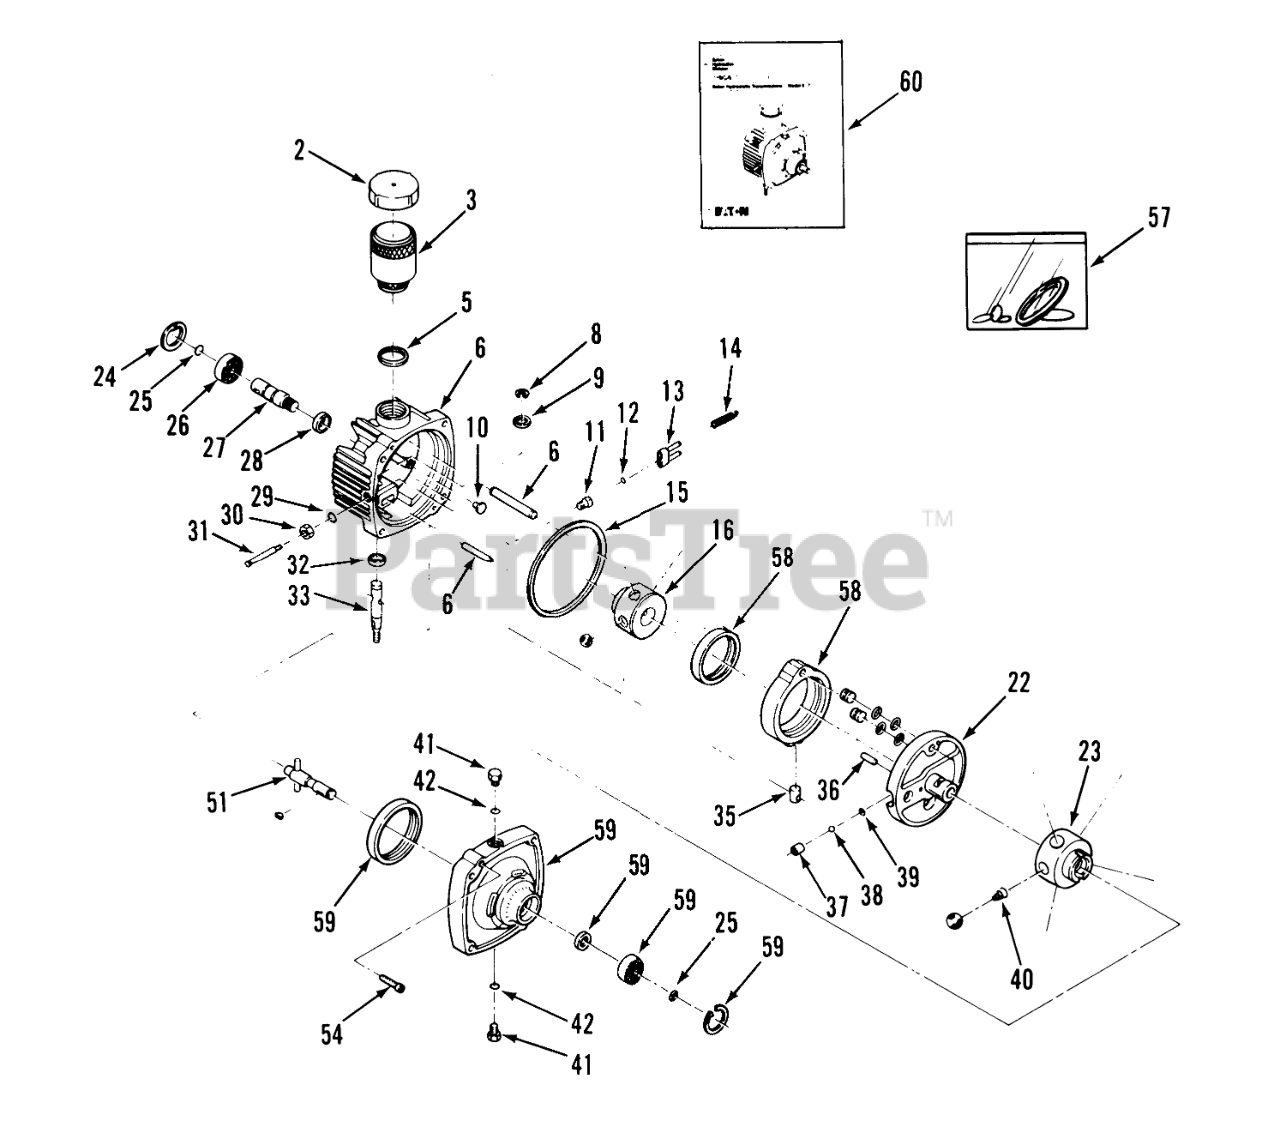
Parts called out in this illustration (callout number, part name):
2	RESERVOIR COVER
3	BODY-RESERVOIR
5	Seal-Ring, Sq (Incl. Item #57)
6	Kit-Cover Service (Incl. Items # 8, 9, 28, 32 & 33)
8	Ring-External Retaining (Incl. Item #6)
9	Washer-Control Shaft (Incl. Item #6)
10	Button
11	Fitting-Guide Assembly, O-Ring (Incl. Item #12)
12	Valve-Bracket (Incl. Items #11 & 57)
13	SUB-ASS'Y BRACKET
14	SPRING-VALVE
15	Seal-Ring, Sq (Incl. Item #57)
16	SUB-ASS'Y PUMP ROTOR
22	Pintle Assembly-Used in CCW rotation trans. Model #00700-023 (Incl. Items #36, 37, 38, & 39)
23	SUB-ASS'Y MOTOR
24	Retaining Ring
25	SNAP-RING
26	BEARING-BALL (INPUT)
27	SHAFT-INPUT
28	Seal-Oil (Incl. in Items #6 & 57)
29	O-Ring-Dump Valve (Incl. Item #57)
30	Gasket Assembly (Incl. Item # 57)
31	PULLEY FLAT B
32	Seal-Oil (Incl. in Items #6 & 57)
33	Kit-Control Shaft (Incl. in Item #6)
35	INSERT-CAM RING
36	Pin-Coil (Incl. Item # 22)
37	Body-Check Valve (Incl. Item #22)
38	Ball-Grade 200 5/16 O.D. (Incl. Item #22)
39	Ring-Retaining (Incl. Item #22)
40	Spring-Piston (Incl. Item #23)
41	Plug Assembly-O-Ring (Incl. Item 42)
42	O-Ring-Tube Fitting (Incl. Items #41 & 57)
51	Shaft Assembly-Output (Incl. Item #59)
54	Screw
57	Kit-Overhaul Sealing (Incl. Items #5, 11, 12, 15, 28, 29, 30, 32, & 42)
58	Ring Sub-Assembly-Cam (Incl. Pump Race & Cam Ring)
59	Body Assembly (Incl. Body, Oil Seal, Output Ball Bearing, Snap Ring, Retaining Ring, Motor Race, & Item #51)
60	Hydrostatic Transmission Repair Manual
